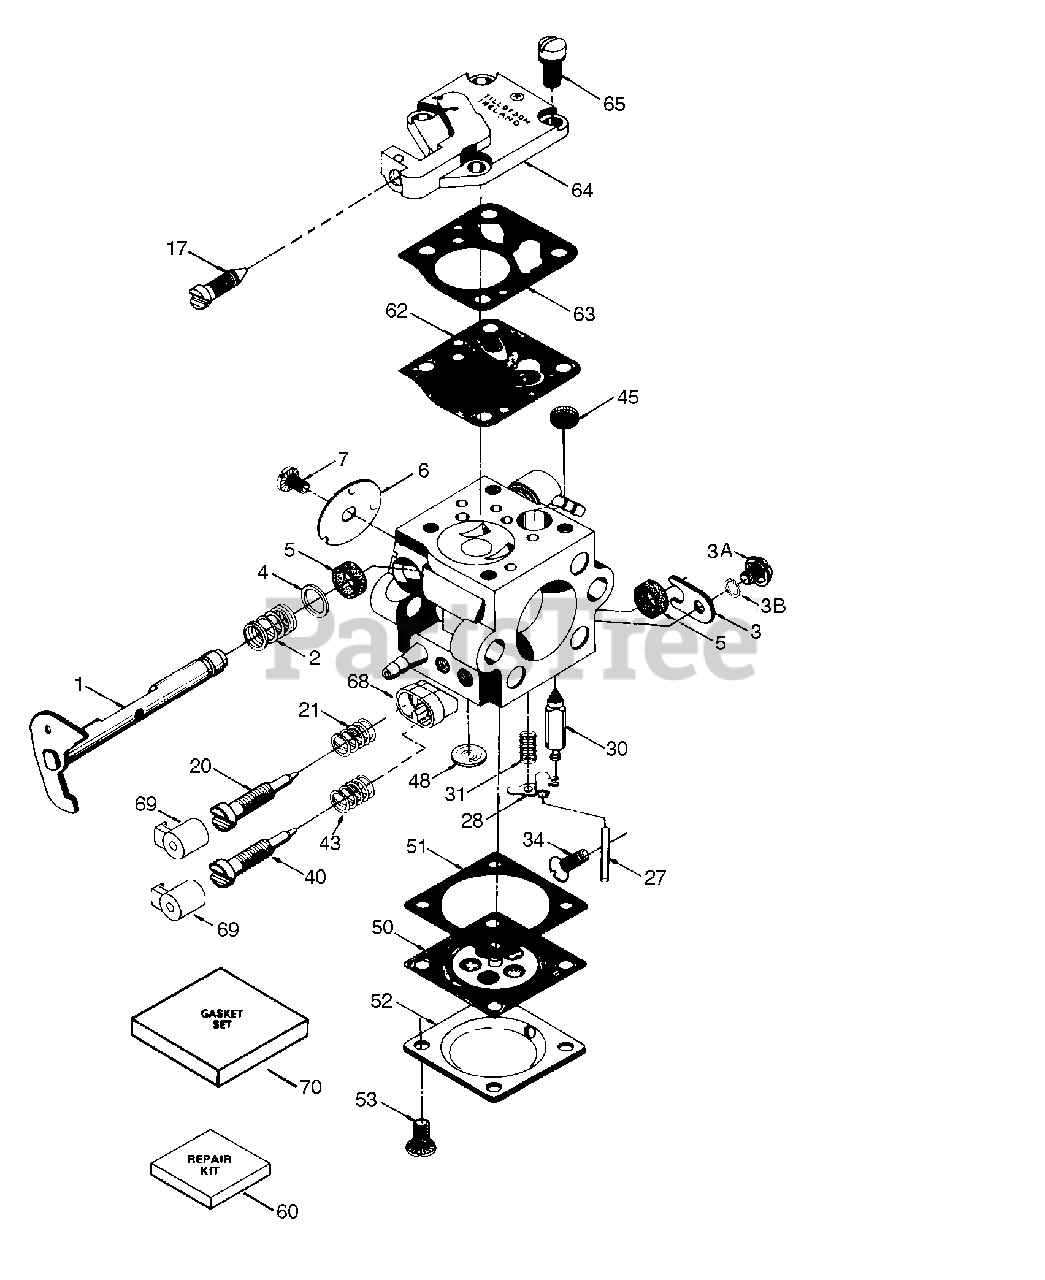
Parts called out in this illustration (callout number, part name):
1	Throttle Shaft & Lever Ass'y.
2	Throttle Return Spring
3	Dust Seal Retainer
3A	Dust Seal Retainer Screw
4	Dust Seal Washer
5	Dust Seal
6	Throttle Shutter
7	Throttle Shutter Screw
17	Idle Speed Screw
20	Idle Mixture Screw
21	Idle Tension Spring
27	Hinge Pin
28	* Metering Lever
30	* Inlet Needle
31	Metering Lever Spring
34	Metering Lever Pin Screw
45	* Fuel Inlet Screen
48	* Welch Plug
50	* Diaphragm (Included in 60 & 70)
51	* Cover Gasket (Included in 60 & 70)
53	Cover Screw
60	Repair Kit (Incl. items marked PK in notes) Incl. (1) each of part #'s6329 02, 632903, 632904, 632907,632908, 63 2915, 632918, 632919
61	Module Clamp Screw
62	* Pump Diaphragm (Included in 60 & 70)
63	* Pump Gasket (Included in 60 & 70)
64	Pump Cover
65	Pump Cover Screw
68	Adjustment Limiter Module
69	Adjustment Limiter Cap
70	Diaghragm/Gasket Set Incl. 50, 51, 62 & 63
